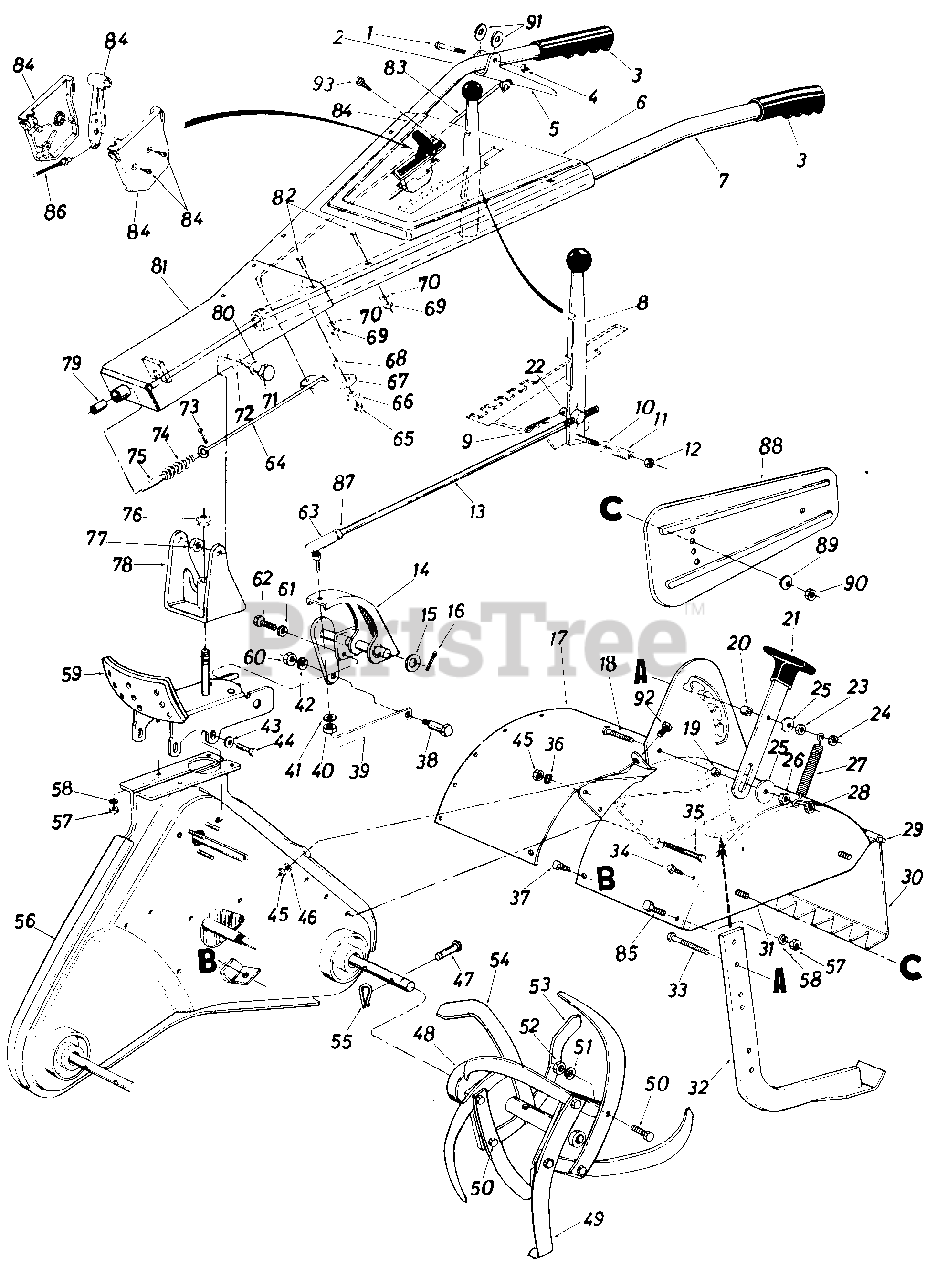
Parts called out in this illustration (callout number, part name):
1	Hex Bolt 1/4-20 x 1.75" Lg.
2	Handle-R.H.
3	Grip
4	Hex Cent. L-Nut 1/4-20 Thd.
5	Clutch Grip
6	Handle Panel Ass'y.
7	Handle-L. H .
8	Clutch Handle Ass'y.
9	Hairpin Cotter
10	Belleville Wash. .38" I.D.
11	Compression Spring .88" O.D. x .81 " Lg.
12	Hex Cent. L-Nut 3/8-24 Thd.
13	Gear Shift Rod
14	Pivot Horn Ass'y.
15	Fl-Wash. .630 I.D. x 1.0" O.D. x .063
16	Cotter Pin 1/8" Dia. x .75"
17	Tine Shield Ass'y.
18	Hex Bolt 3/8-16 x 1.5" Lg.
19	Spacer .38 I.D. x .50 O.D. x .18 Lg.
20	Spacer .38 I.D. x .50 O.D. x .38 Lg.
21	Depth Bar Handle Ass'y. w/ Knob
22	Ferrule
23	Hex Nut 3/8-16 Thd.
24	Hex Ins. L-Nut 3/8-16 Thd.
25	Fl-Wash. .38 I.D. x 1.50 O.D. x . 1 3
26	Hex Nut 3/8-16 Thd.
27	Spring-Depth Bar
28	Hex Ins. L-Nut 3/8-16 Thd.
29	Hinge Rod
30	Tine Shield Hinge Flap Ass'y.
31	Side Cover Tine Shield-L.H.
32	Depth/Drag Bar Ass'y.
33	Hex Bolt 3/8-16 x 1.75" Lg.
34	Hex Wash. Hd. Self-Tap Scr. 5/16-18 x .62" Lg.
35	Hex Bolt 3/8-24 x 3.0" Lg.
36	L-Wash. 3/8" I.D.
37	Hex Wash. Hd. Self-Tap Scr.
38	Shoulder Bolt .50" Dia. x .25"
39	Control Bracket
40	Hex Ins. L-Nut 3/8-24 Thd.
41	L-Wash. 3/8" I.D.
42	L-Wash. 3/8" I.D.
43	Belleville Wash.
44	Hex Wash. Hd. Self-Tap Scr.
45	Hex Nut 3/8-24 Thd.*
46	L-Wash. 3/8" I.D.
47	Clevis Pin
48	Tine Adapter Ass'y.
49	L.H. Tine Ass'y. Comp.
50	Hex Bolt 3/8-24 x 1.25" Lg.
51	L-Wash. 3/8" I.D.*
52	Hex Nut 3/8-24 Thd.
56	Chain Case Ass'y. Comp.
57	Hex Nut 5/16-18 Thd.
58	L-Wash. 5/16" I.D.
59	Handle Positioner Ass'y.
60	Hex Ins. L-Nut 3/8-16 Thd.
61	L-Wash. 5/16" I.D.
62	Hex Wash. Hd. Self-Tap Scr.
63	Rod End 3/8-24 Thd.
64	Lower Handle Control Rod
65	Hex Nut 5/16-18 Thd.
66	Pivot Handle Brg.
67	Pivot Handle Link
68	Bushing Wash.
69	Hex Nut 5/16-18 Thd.
70	L-Wash. 5/16" I.D.
71	Shld. Bolt .500" Dia. x .660
72	Belleville Wash. .505" I.D. x 1.00" O.D.
73	Cotter Pin 1/8" Dia. x .75"
74	Compression Spring
75	Locking Pin
76	Hex Ins. L-Nut 5/8-16 Thd.
77	Hex Top L-Nut 3/8-16 Thd.
78	Pivot Brkt. Ass'y.
79	Sleeve Brg. .50" I.D. x .62" O.D. x 1.12" Lg.
80	Fl-Wash. .50" I.D. x 1.00" O.D. x .090
81	Handle Mtg. Brlst. Ass'y.
82	Carriage Bolt 5/16-18 x 1.75"
83	Handle Lock Rod
84	Throttle Control Box Ass'y.
85	Hex Bolt 5/16-18 x .75" Lg.
86	Throttle Control Wire
87	Hex Jam Nut 3/8-24 Thd.
90	Hex Nut 5/16-18 Thd.
91	Fl-Wash. 1/4" I.D.
92	Hex Bolt 3/8-24 x .75" Lg.
93	Self-Tap Scr. #10 x 1/2" Lg.
